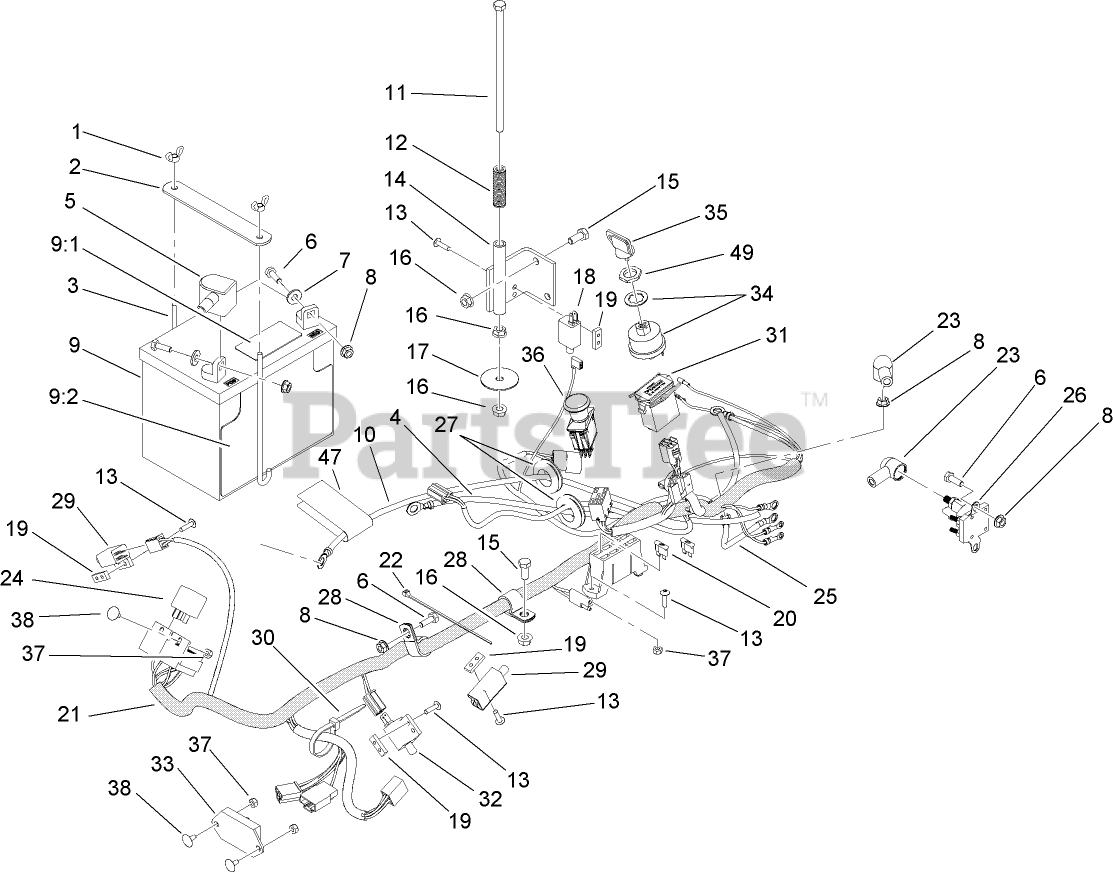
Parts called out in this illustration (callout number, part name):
1	WINGNUT
2	STRAP-HOLDDOWN, BATTERY
3	BOLT-HOLDDOWN
4	CABLE-GROUND, NEGATIVE
5	INSULATOR-BATTERY
6	SCREW-HH
7	WASHER-FLAT
8	NUT-HF
9	BATTERY
9:1	Decal-Battery
9:2	Decal-Battery
10	CABLE-BATTERY, POSITIVE
11	SCREW-HH
12	SPRING-SWITCH, SEAT
13	SCREW-HEAD, TRUSS
14	BRACKET-SWITCH, SEAT
15	SCREW-HH
16	NUT-HF
17	WASHER
18	SWITCH-CLOSED, NORMALLY
19	PLATE-TAPPED
20	FUSE-BLADE TYPE, 20 AMP
21	HARNESS-ELECTRICAL
22	TIE-CABLE
23	INSULATOR-SOLENOID
25	CABLE-STARTER, POSITIVE
26	SWITCH-SOLENOID
27	GROMMET
28	CLIP-LOOM
29	SWITCH-OPEN, NORMALLY
30	TIE-PLASTIC
31	METER-HOUR
32	SWITCH
33	MODULE-DELAY, SEAT
34	SWITCH-STARTING, KEY
35	KEY-IGNITION
36	SWITCH-PTO
37	NUT-LOCK, NI
38	BOLT-CARR
47	DECAL-INSTRUCTIONS, CHARGING
49	NUT-SWITCH, IGNITION
